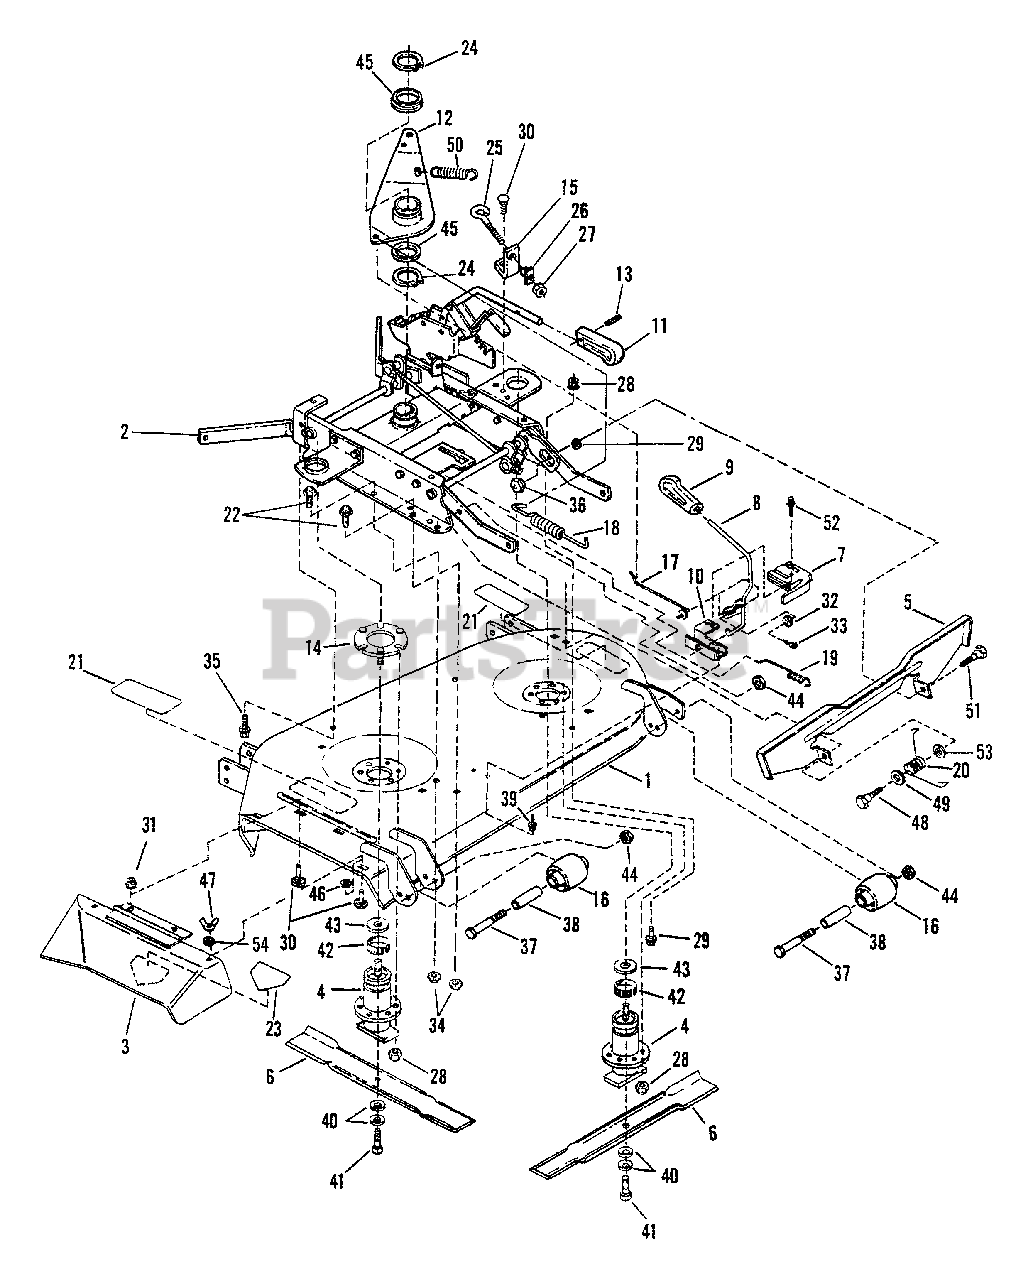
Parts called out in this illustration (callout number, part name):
1	ASSEMBLY, Deck
2	ASSEMBLY, Rail
3	ASSEMBLY, Side Chute
4	ASSEMBLY, Spindle
5	ASSEMBLY, Pedal
6	21" BLADE
7	SWITCH, Deck Interlock
8	LEVER, Blade Engagement
9	GRIP, Handle
10	MOUNT, Handle
11	GRIP, Height Adjustment Lever
12	ARM, Idler
13	PIN, 3/16 x 3/4" Roll
14	ASSEMBLY, Spindle Ring
15	ANCHOR
16	ROLLER
17	ROD, Idler
18	SPRING, Belt
19	SPRING, Latch
20	SPRING, Pedal
21	DECAL, Caution
22	BOLT, 5/16-18 x 5/8" Hex Flange Lock
23	DECAL, Danger
24	RING, 2" External Retaining
25	BOLT, 1/4-20 Eye
26	T-NUT, 1/4-20
27	NUT, 1/4-20 Hex
28	NUT, 3/8-16 Hex Lock
29	WASHER, 3/8 Internal Tooth Lock
30	BOLT, 5/16-18 x 3/4" Carriage
31	NUT, 5/16-18 Hex Flange Lock
32	WASHER, 1/4 Flat
33	PIN, 3/32 x 3/4" Cotter
34	NUT, 5/16-18 Hex Flange Lock
35	SCREW, 5/16-18 x 5/8" Self-Tapping
36	ECCENTRIC, Leveling
37	SCREW, 3/8-24 x 3-3/4" Hex Head Cap
38	SPACER
39	SCREW, 1/4-20 x 5/8" Self-Tapping
40	WASHER, Cone
41	SCREW, 3/8-24 x 1" Hex Head Cap
42	RING, Tolerance
44	NUT, 3/8-24 Hex Lock
45	WASHER, 2" I.D. Nylon
46	RETAINER, 5/16 Bolt
47	NUT, 5/16-18 Wing
48	BOLT, 3/8-24 x 9/16" Shoulder
49	WASHER, 1/2 Flat
50	SPRING, Return
51	BOLT, 3/8-24 x 3/4" Shoulder
52	SCREW, #10-32 x 1" Self-Tapping
53	WASHER, 3/8" Flat
54	WASHER, 5/16 Flat
